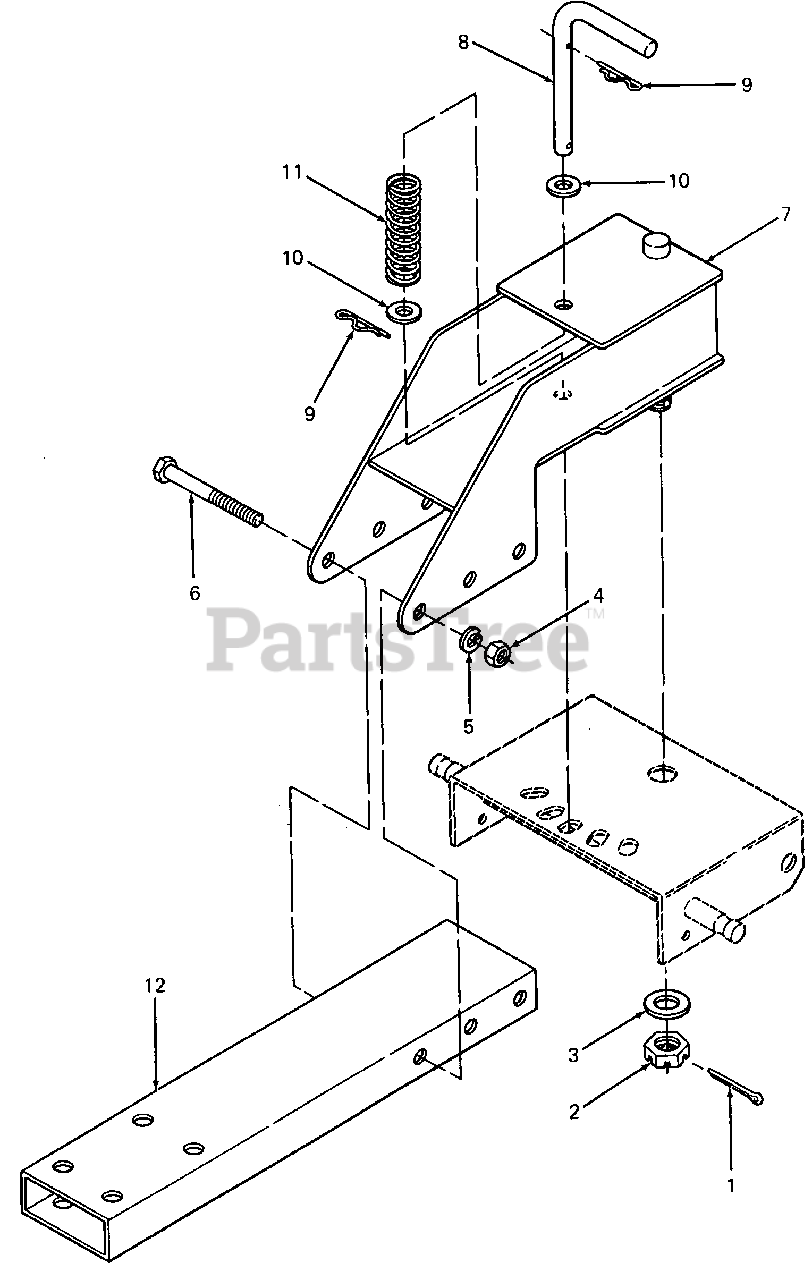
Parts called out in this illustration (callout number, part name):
1	Pin, Cotter, 1/8 Dia X 1-5/8 Lg
2	Nut, Hex Castle, 3/4-16 GR5
3	Washer, Flat, .812 X 1.47 X .108 Thk
4	Nut, Hex, 3/8-24
5	Washer, Lock, 3/8
6	Screw, Hex Cap, 3/8-24 X 3.75 Lg GR5
7	Bracket, Pivot
8	Handle, Pivot Bracket
9	Pin, Internal Cotter
10	Washer, Flat, .510 X 1.0 X .060 Thk
11	Spring, Compression
12	Tubing, Rectangular, 2 X 3 X 21.0 Lg
